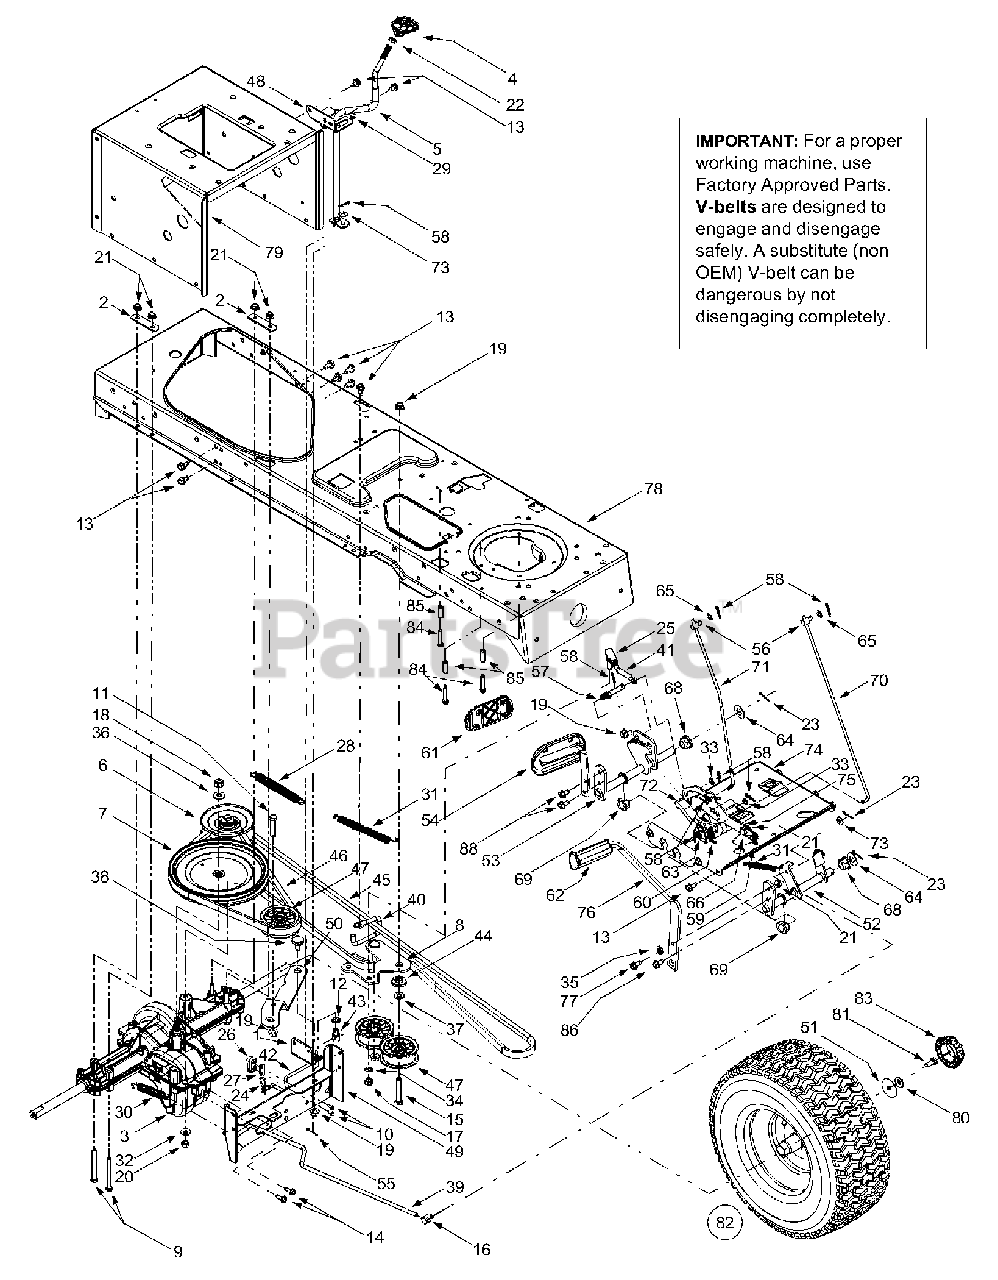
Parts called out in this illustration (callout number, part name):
3	Single-speed Transmission Assembly
4	Shifter Knob
5	Shift Lever
6	Variable-speed Pulley Assembly
7	Transmission Pulley, 8.5 x .5-36
8	Double-idler Bracket
9	Hex Cap Screw, 5/16-18 x 2.75
10	Self-tapping Screw, #8-18 x .5
11	Hex Cap Screw, 3/8-16 x 1.75
12	Flat Washer, .51 x 1.0 x .060
13	Self-tapping Screw, 5/16-18 x .625
14	Self-tapping Screw, 1/4-20 x .75
15	Hex Cap Screw, 3/8-16 x 2.25
16	Ferrule, 5/16-18
17	Hex Nut, 3/8-24
18	Hex Nut, 7/16-20
19	Flange Lock Nut, 3/8-16
20	Hex Nut, 3/8-16
21	Flange Lock Nut, 5/16-18
22	Jam Nut, 3/8-16
23	Cotter Pin
24	Internal Cotter Pin
25	Ball Joint
26	Short Spring Switch
27	Insulator Nut Plate
28	Extension Spring, .62 Dia. x 6.12
29	Compression Spring Clip
30	Extension Spring, .59 OD x 4
31	Extension Spring, .50 Dia. x 6.37
32	Bell Washer, .401 x .87 x .063
33	Flat Washer, .385 x .62 x .063
34	Lock Washer, 3/8
35	Flat Washer, .344 x .750 x .120
36	Bell Washer, .45 x 1.0 x .602
37	Flat Washer, .407 x .812 x .135
38	Shoulder Screw, .625 x .217
39	Brake Rod
40	Belt Guard
41	Idler Adjustment Rod, 3/8
42	Shift Rod
43	Adjustment Ferrule, 1/4-20 x 1.0
44	Shoulder Spacer, .38 ID
45	Lower Drive Belt
46	Upper Drive Belt
47	Flat Idler, 2.75 OD
48	Speed Control Rod Bracket
51	Flat Washer, .350 x 1.59 x .062
52	Brake Control Assembly
53	Speed Control Assembly
54	Drive Pedal Assembly
55	Cotter Pin, 1/8 x 1.25
56	Ferrule, 1/4-20
57	Pin, 3/8-16 x 2.43
58	Cotter Pin
59	Compression Spring, .34 OD x 1.0
60	Extension Spring, .50 OD x 1.41
61	Drive Pedal Pad
62	Brake Pedal Pad
63	Flat Washer, .281 x .5 x .063
64	Flat Washer, .64 x 1.24 x .06
65	Flat Washer, .344 x .062 x .03
66	Shoulder Screw, .437 x 1.62
67	Shoulder Screw, .5 x .434
68	Hex Flange Bearing
69	Split Hex Flange Bearing
70	Cruise Control Rod
71	Brake Lock Control Rod
72	Cruise Latch
73	Flat Washer, .344 x .688 x .065
75	Drive Lockout Bracket
81	Hex Cap Screw, 5/16-24 x .75
83	Deluxe Hub Cap
84	Self-tapping Screw, 1/4-20 x 1.25
85	Spacer
86	Self-tapping Screw, 5/16-18 x .875
